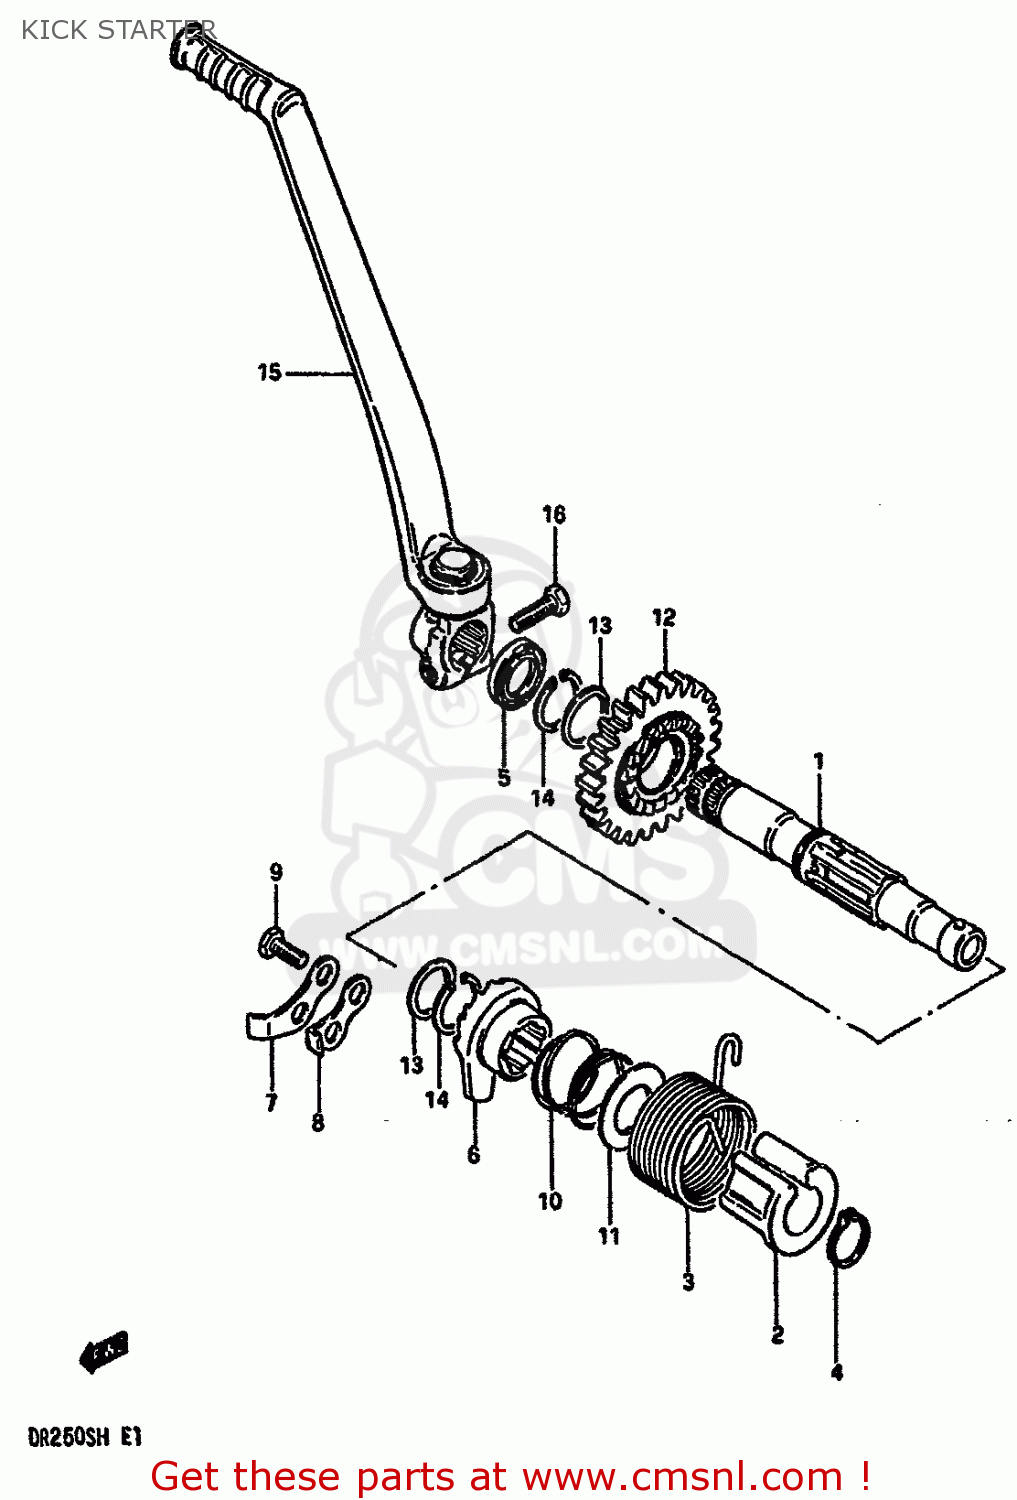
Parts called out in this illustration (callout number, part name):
1	SHAFT,KICK STARTER
2	GUIDE,KICK STARTER SFT SPRING
3	SPRING
4	CIRCLIP
5	SEAL,OIL(20X27X5)
6	STARTER,KICK
7	GUIDE,KICK STARTER
8	STOPPER,KICK STARTER
9	BOLT
10	SPRING
11	WASHER
12	GEAR,KICK STARTER DRIIVE
13	SHIM
14	CIRCLIP
15	LEVER ASSEMBLY,KICK STARTER
16	BOLT 8X25
